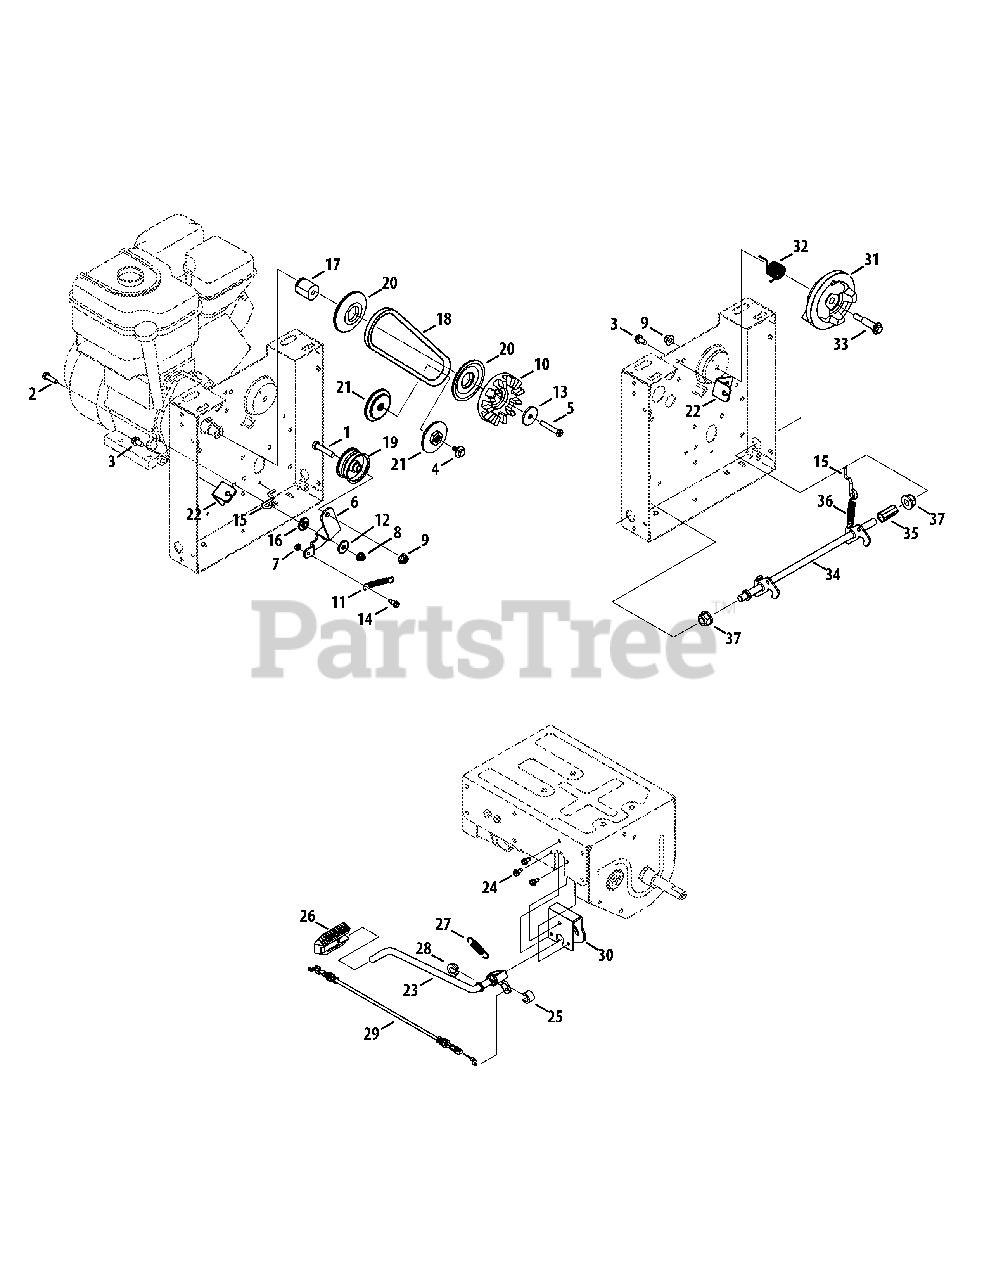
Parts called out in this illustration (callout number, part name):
1	Hex Cap Screw, 3/8-16 x 1.75
2	Hex Cap Screw, 5/16-18 x 1.00
3	Hex Washer Screw, 5/16-18 x .750
4	Hex Cap Screw, 5/16-24 x .750
5	Hex Cap Screw, 5/16-24 x 1.88
6	Idler Bracket
7	Hex Lock Nut, 1/4-20
8	Flange Lock Nut, 5/16-18
9	Flange Lock Nut, 3/8-16
11	Extension Spring, 2.675
12	Flat Washer, 1.0 OD x .331 ID
13	Flat Washer, .340 x 1.50 x .150
14	Shoulder Screw, 1/4-20 x .3175 x .188
15	Spring Hook Rod
16	Shoulder Spacer
17	Spacer, .875 ID x 1.255 OD
19	Idler Pulley, 2.46 OD
20	Half Pulley, 3.4 Dia.
21	Half Pulley, 2.6 Dia.
22	PTO Cable Bracket
23	Lever Rod Assembly
24	Hex Washer Screw, 1/4-20 x .500
25	Spacer, .500 ID x .500 Lg
26	Kickstand Cover
27	Extension Spring, .50 OD x 2.142
28	Hex Flange Bearing, .500 ID
29	Control Cable, 12.75"
30	Kick Stand Release Lever Bracket
31	Lug Actuator
32	Torsion Spring, RH
33	Shoulder Screw, .498 x 1.635
34	Lock Latch Assembly
35	Spacer, .515 ID x 1.500 LG
36	Extension Spring, .500 Dia x 2.733 Lg
37	Flange Bearing, .50 ID
